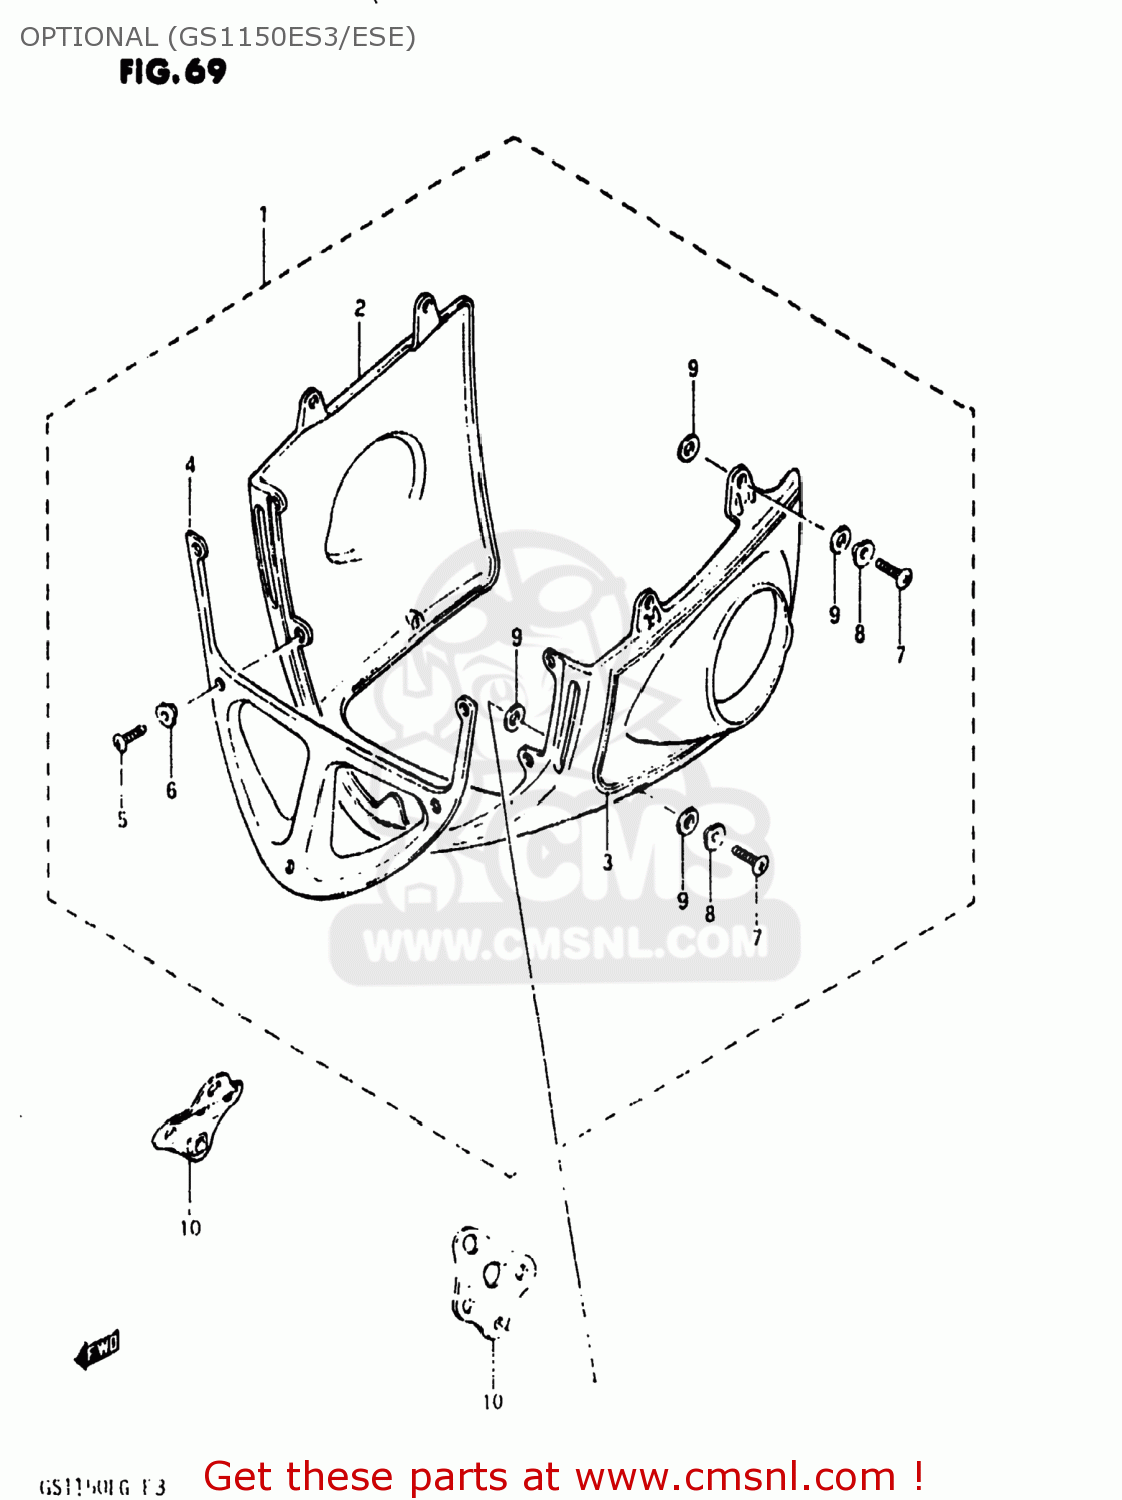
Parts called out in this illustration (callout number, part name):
1	COWLING LOWER SET WHITE/RED
2	COVER,COWLING,LOWER
3	TAPE SET,COWLING
4	COVER,LOWER,CENTER
5	SCREW
6	WASHER
7	SCREW
8	WASHER
9	WASHER(6X13X2)
10	PLATE,ENGINE MOUNTING NO
